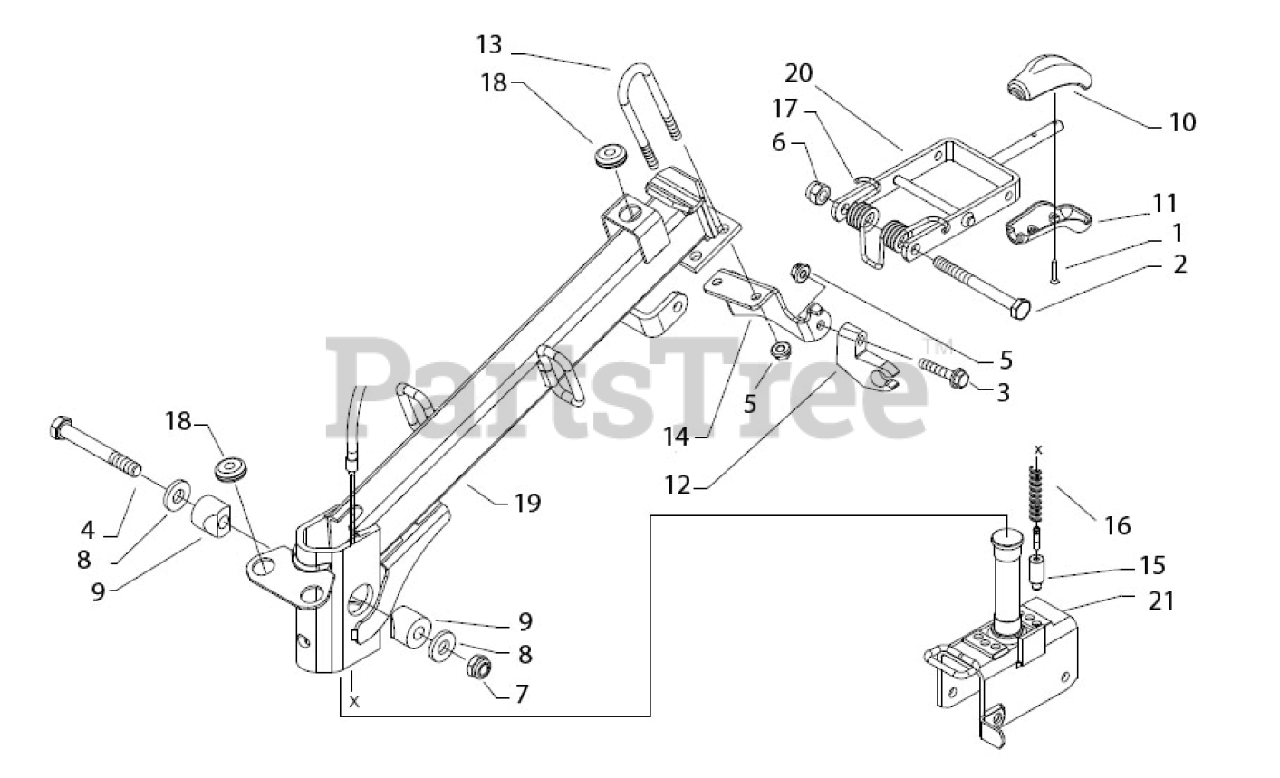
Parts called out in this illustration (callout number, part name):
1	SCREW 3,5X25
2	SCREW TE M10X110
3	SCREW TE C/F M8X35
4	SCREW TE M12X80
5	SELFLOCK NUT M8
6	SELFLOCK NUT M10
7	SELFLOCK NUT M12
8	CUP SPRING
9	WEDGE
12	SUPPORT
13	U BOLT
14	SUPPORT BRACKET
15	FERRULE
16	SPRING
17	SPRING
18	GROMMET, GUARD SUPPORT
19	STEERING COUMN
20	LEVER
21	CONNECTION
